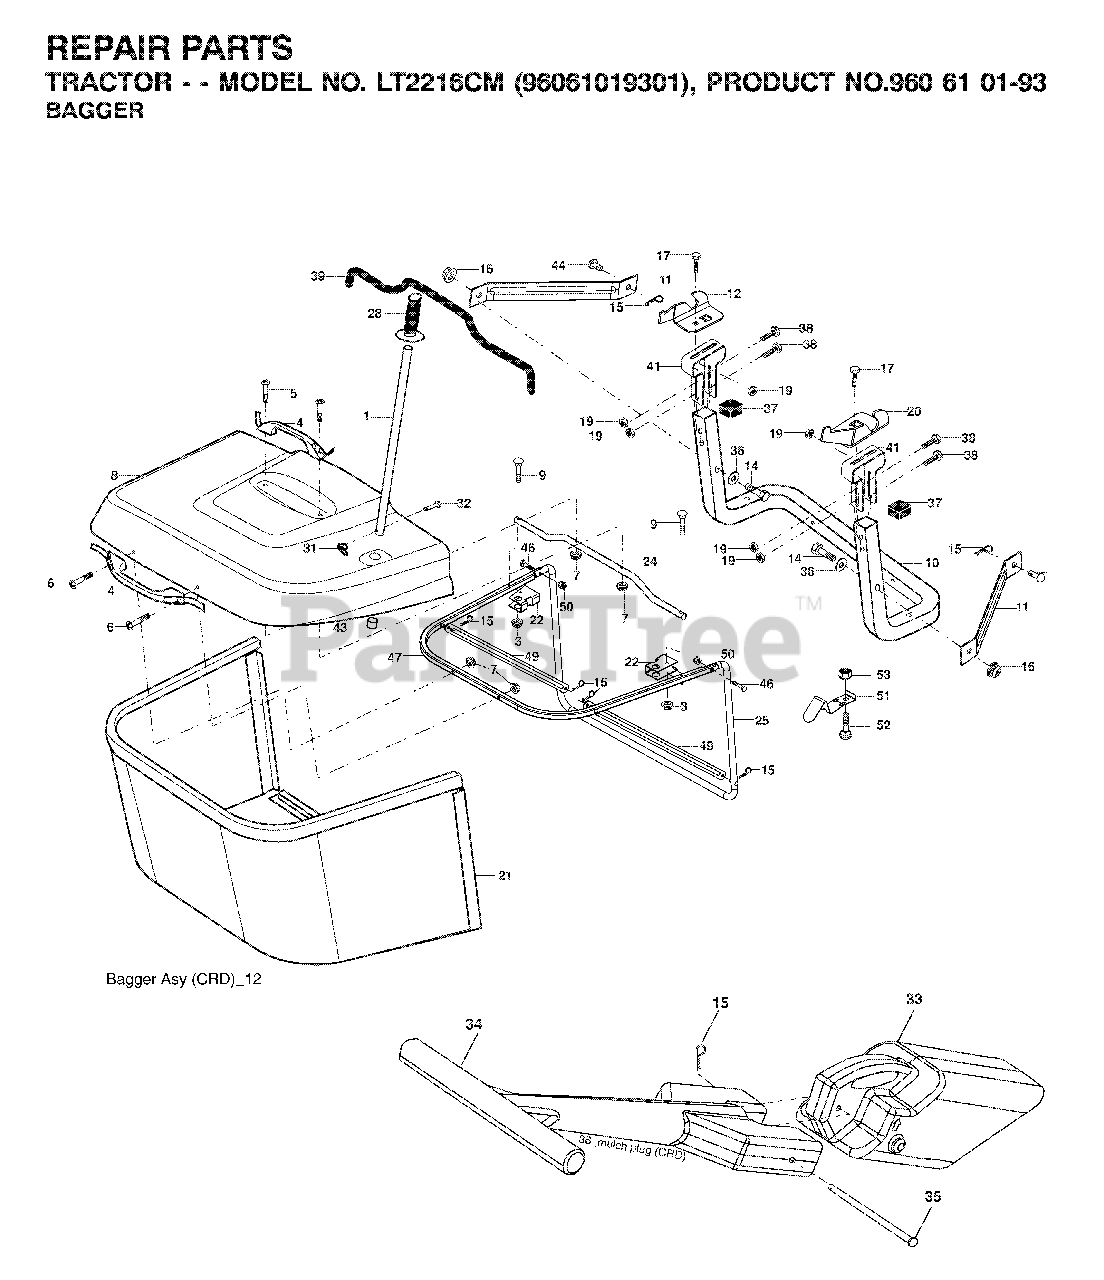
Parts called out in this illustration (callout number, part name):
1	TUBE HANDLE
3	NUT T
5	SCREW.PAN.HEAD
11	BRACKET
14	BOLT-HEX EAK
15	RETAINER-SPRNG RB
16	NUT LOCK FLG 3/8-16 UNC
17	BOLT
19	NUT LOCK HEX FLANGE 5/16-18
20	BRKT.PIVOT.RH.CRD
21	BAGGER.ASM.CRD.2007
22	BRACKET
24	TUBE
28	GRIP.HANDLE.BLACK
31	RETAINER CLIP
32	RIVET,DRILLED
33	PLUG
35	PIN
38	BOLT.5/16-18X2.5
41	BRKT, BAGGER
43	PLUG, TUBING END
46	BOLT.CARRIAGE.5/16-18
50	NUT.71038.31-18.HEX.NYLOCK
52	BOLT
53	NUT
